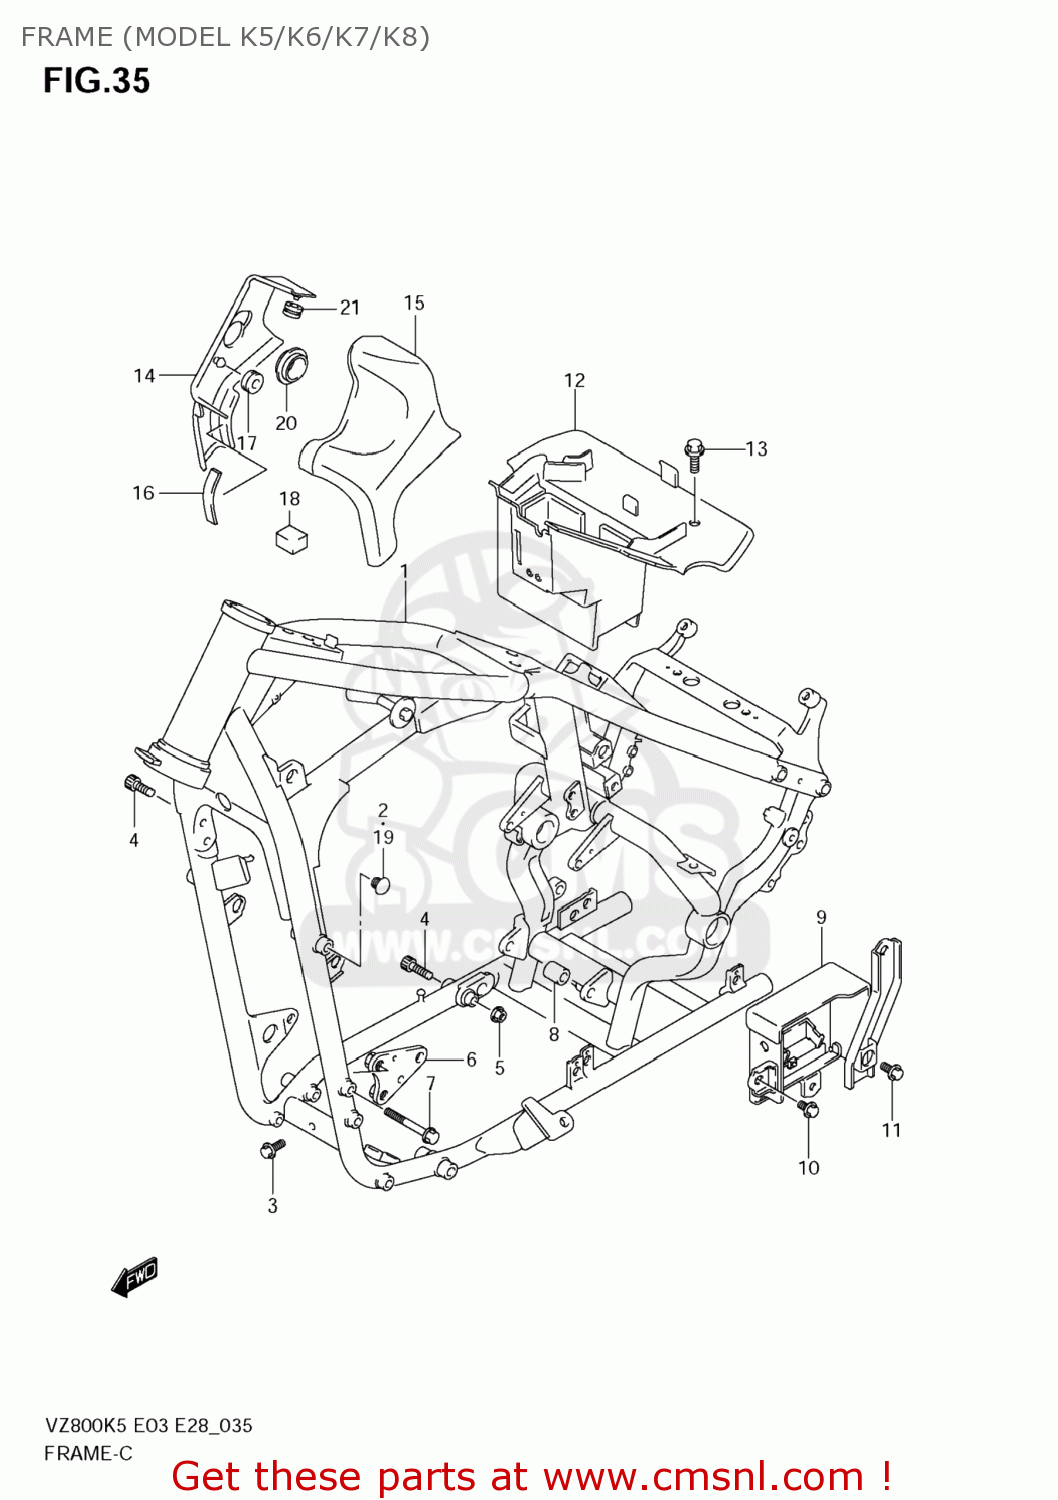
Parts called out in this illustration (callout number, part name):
1	FRAME(BLACK)
2	CAP(OD:14)
3	BOLT
4	BOLT
5	NUT
6	PLATE,ENGINE MOUNT NO.1,L
7	BOLT(8X65)
8	SPACER,ENG MTG LR
9	HOLDER COMP,EL
10	BOLT
11	BOLT
12	HOLDER,ELECTRI
13	BOLT(6X16)
14	COVER,FRAME HEAD,R(BLACK)
15	COVER,FRAME HE
16	CUSHION,FR FENDER
17	CUSHION
18	CUSHION,RADIATOR COVER INNER
19	CAP(OD:14)
20	CAP
21	CUSHION
